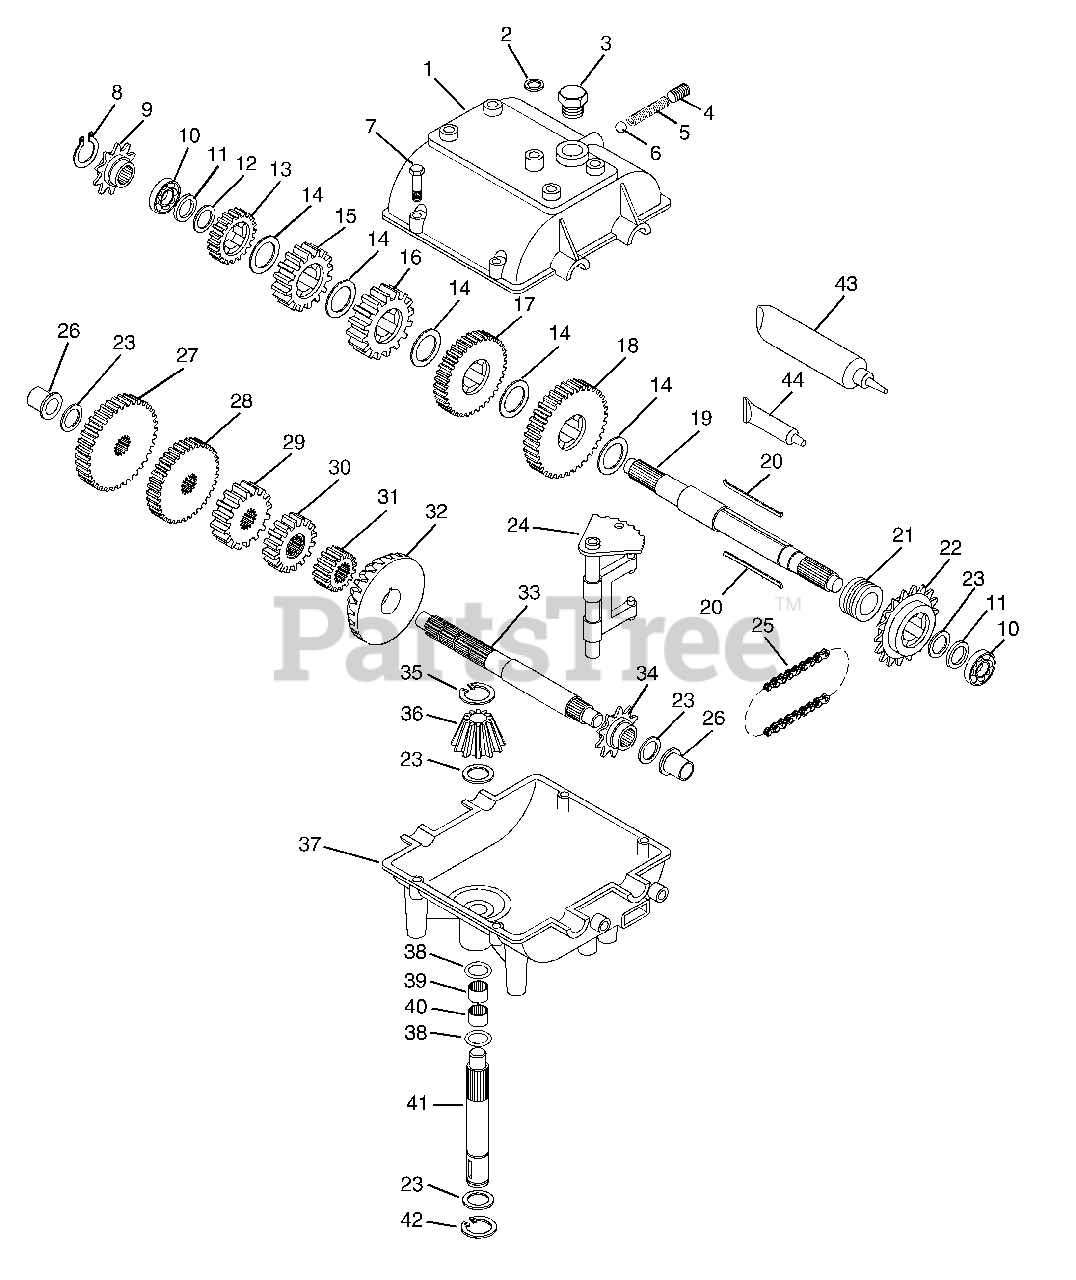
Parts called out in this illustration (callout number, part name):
1	Cover, Transmission
2	Seal, Square Cut
3	Plug, Threaded
4	Screw, Set 3/8-16 x 3/8
6	Ball, Steel 5/16
7	Screw, HHD Taptite 1/4-20 x 1-1/4
8	Ring, Retaining
9	Sprocket (12 Teeth)
10	Bearing, Ball
11	Washer, Thrust
12	Washer, Thrust
13	Gear, Spur (20 Teeth)
14	Washer, Thrust
15	Gear, Spur (22 Teeth)
16	Gear, Spur (25 Teeth)
17	Gear, Spur (30 Teeth)
18	Gear, Spur (35 Teeth)
19	Shaft, Output & Brake
21	Collar, Shift
22	Sprocket (18 Teeth)
23	Washer, Thrust
24	Rod & Fork Assembly, Shift
25	Chain, Roller (No. 41 Chain, 24 Links)
26	Bushing, Flanged
27	Gear, Spur (30 Teeth)
28	Gear, Spur (28 Teeth)
29	Gear, Spur (25 Teeth)
30	Gear, Spur (20 Teeth)
31	Gear, Spur (15 Teeth)
32	Gear, Bevel (42 Teeth)
33	Shaft, Counter
34	Sprocket (9 Teeth)
35	Ring, Retaining
36	Bevel Pinion, Input
37	Case, Transmission
39	Bearing, Needle
40	Bearing, Needle
41	Shaft, Input
42	Ring, Retaining
43	Grease (32 oz. Bottle Bentonite Grease)
44	Gasket Eliminator (Loctite 515)
